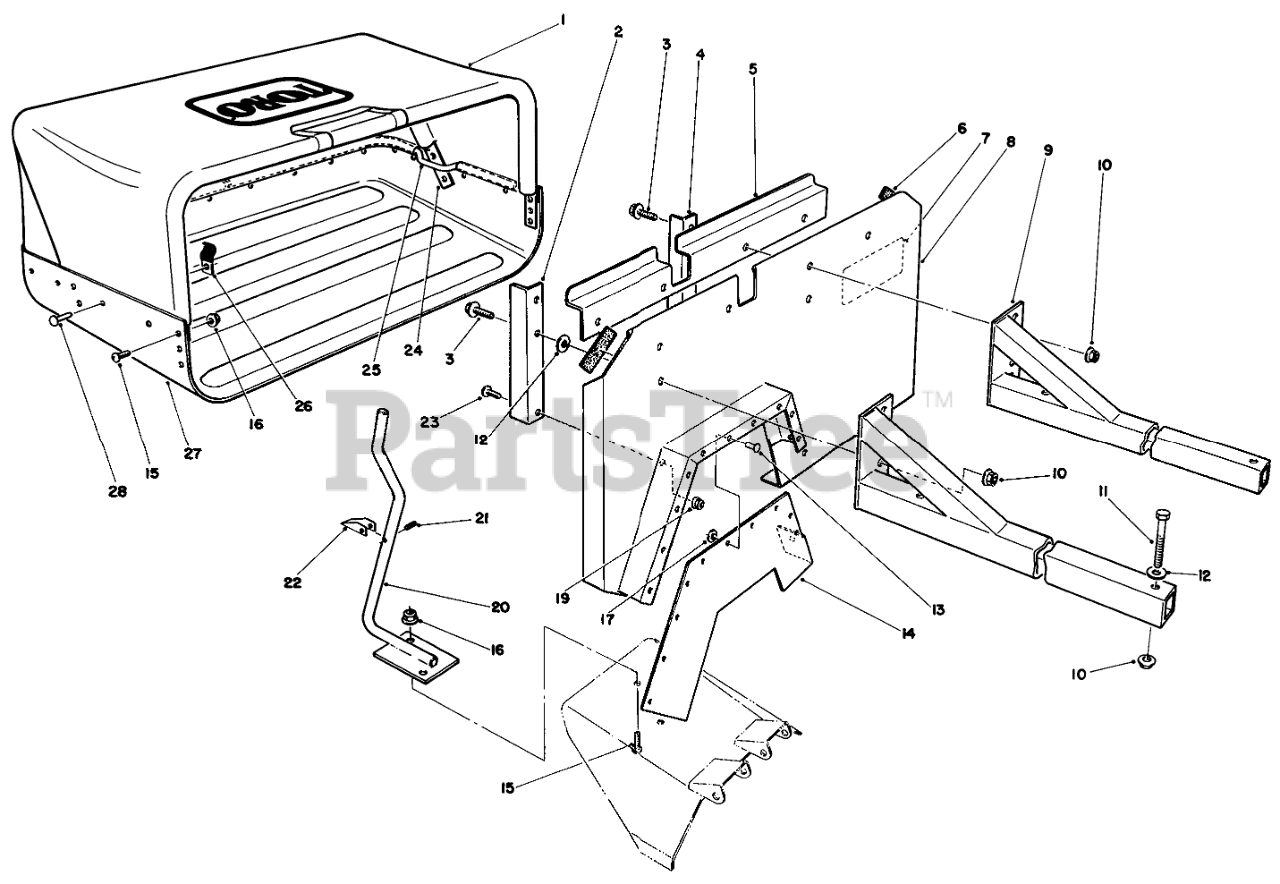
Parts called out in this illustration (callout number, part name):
1	Bag-Cloth
2	Support-Panel, RH
3	SCREW-HHF
4	Support-Panel
5	Support-Bag Attachment
6	PAD-RUBBER
7	DECAL-DANGER
8	Panel-Back
9	Mount-Beam
10	NUT-HHF, WHIZ
11	SCREW-HH
12	WASHER-FLAT
13	RIVET-POP
14	Extension-Rubber
15	SCREW-PPH
16	NUT-HF
17	WASHER-PLAIN
19	NUT-LOCK, HHF
20	Rod-Lockup
21	PIN-SPRING
22	LATCH-LOCKUP
24	Tube-Bag Support
25	Rod-Cloth
26	CLIP-HALF
27	TRAY-BAG, GRASS
28	RIVET-BLIND
